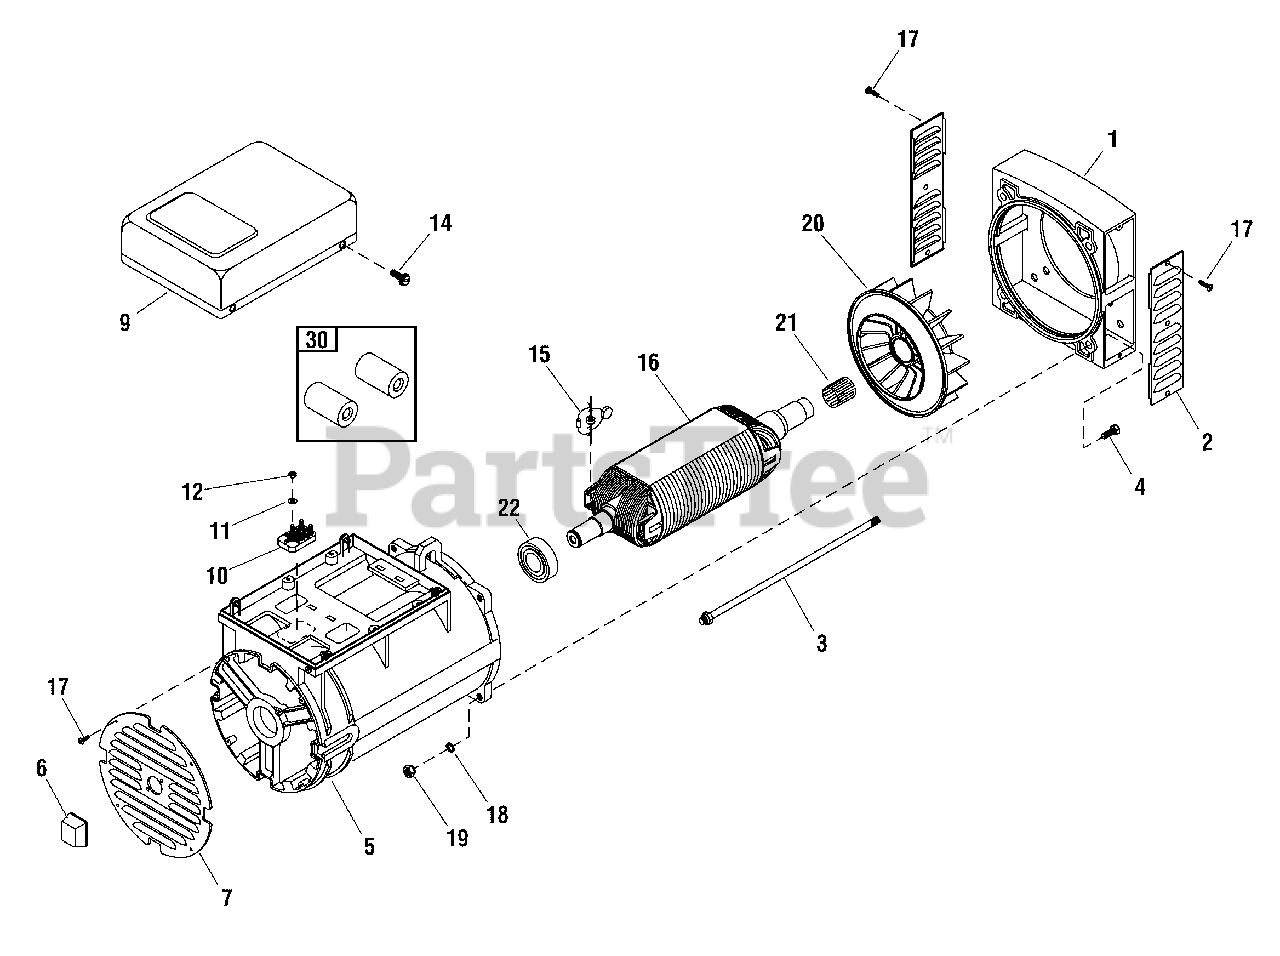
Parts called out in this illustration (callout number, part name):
1	ADAPTER, Engine
7	COVER, Rear Bearing
9	COVER, Capacitor
10	BLOCK, Terminal
11	* WASHER, Flat, #10-M5
12	* NUT, 10-32
14	* SCREW, Phillips Head, 10-32 x 3/4
15	DIODE
17	* SCREW, M8 x 1.25 x 35mm
18	* WASHER, Shakeproof, EXT. M6-1/4
19	* NUT, 1/4-20
30	VERIFY MICROFARAD (uF) RATING BEFORE ORDERING. REPLACEMENT CAPACITORS MUST MATCH ORIGINALS. IN MULTIPLE CAPACITOR SYSTEMS, IF ONE CAPACITOR IS NOT WORKING ALL CAPACITORS MUST BE REPLACED.
